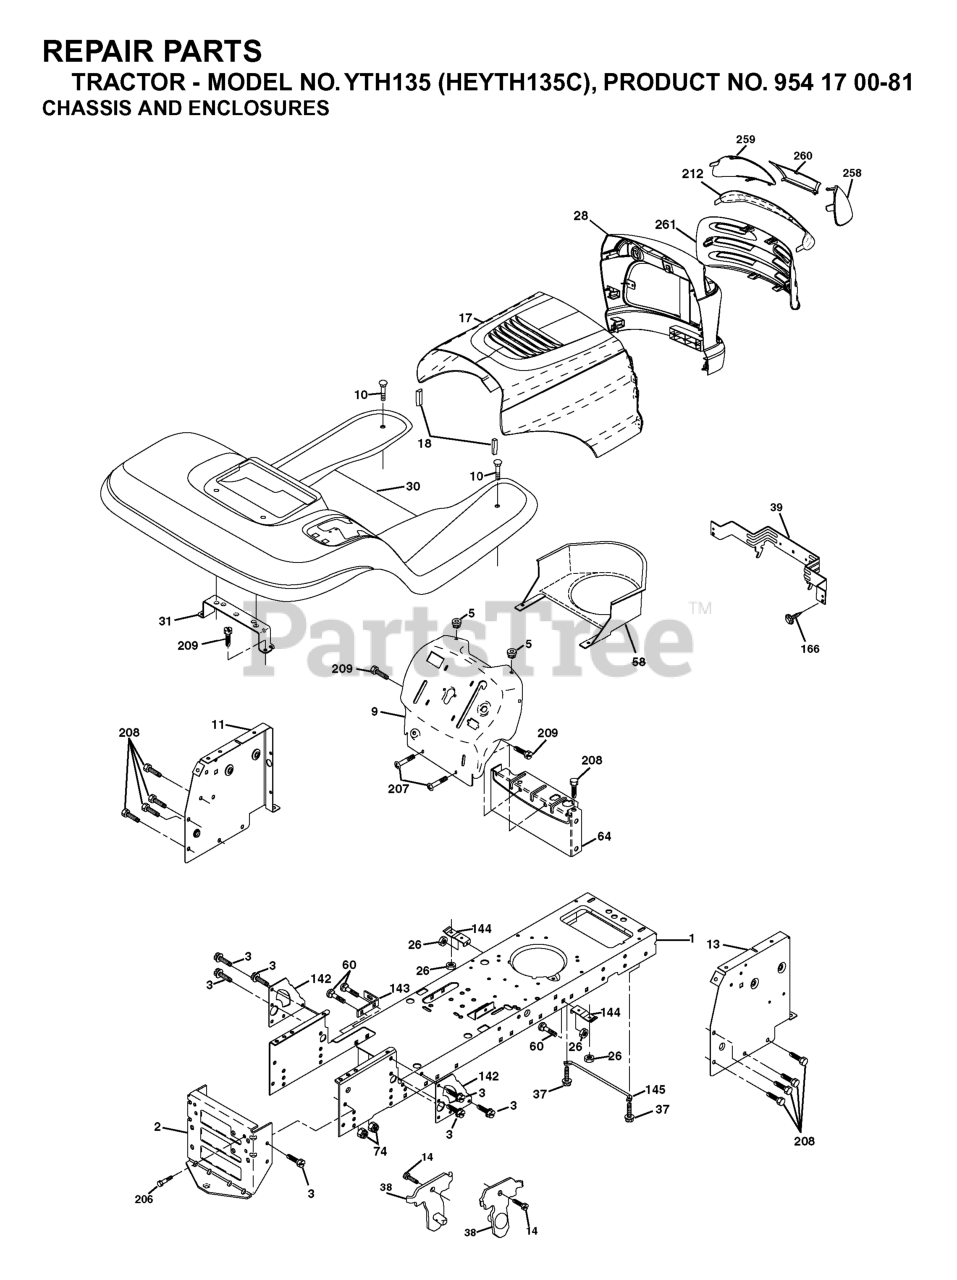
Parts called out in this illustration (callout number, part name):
1	CHASSIS STAMPING
2	DRAWBAR, 12GA
3	SCREW 3/8-16X3/4
5	BUMPER.RUBBER.HOOD
9	DASH
10	BOLT D
11	PANEL.DASH.LH.LTX
13	PANEL DASH RH
17	HOOD
18	BUMPER.HOOD.LARGE.1.75"
20	PLATE MTG.BATTERY/FUEL TANK
23	BUSHING.SNAP.NYL.BLK.
26	NUT
30	FENDER FOOTREST
31	BRACKET.SUPPORT.FENDER
37	Screw 5/16-18 x 1/2 Hex, Self Tapping 5/16-18 x 1/2
38	BRACKET.ASM.PIVOT.MOWER.REAR
39	BRACKET PIVOT LASER
60	Bolt - Rd. Hd. Sq. Neckiage 3/8 16 x 3/4
64	DASH LOWER
142	PLATE REINFORCEMENT
143	BRACKET, SWAY BAR
144	BRKT, FOOT REST
145	ROD PIVOT CHASSIS/HOOD
166	SCREW
206	SHOULDER BOLT 5/16-18TT
207	SCREW, 5/16-18 X 1/2
208	SCREW 3/8-16X1/2
209	SCREW, 3/8-16X3/4
212	INSERT.LENS.REFLECTIVE
219	SCREW
258	LENS LH
259	LENS LH
260	COVER.LENS.HUSQ.LASER
